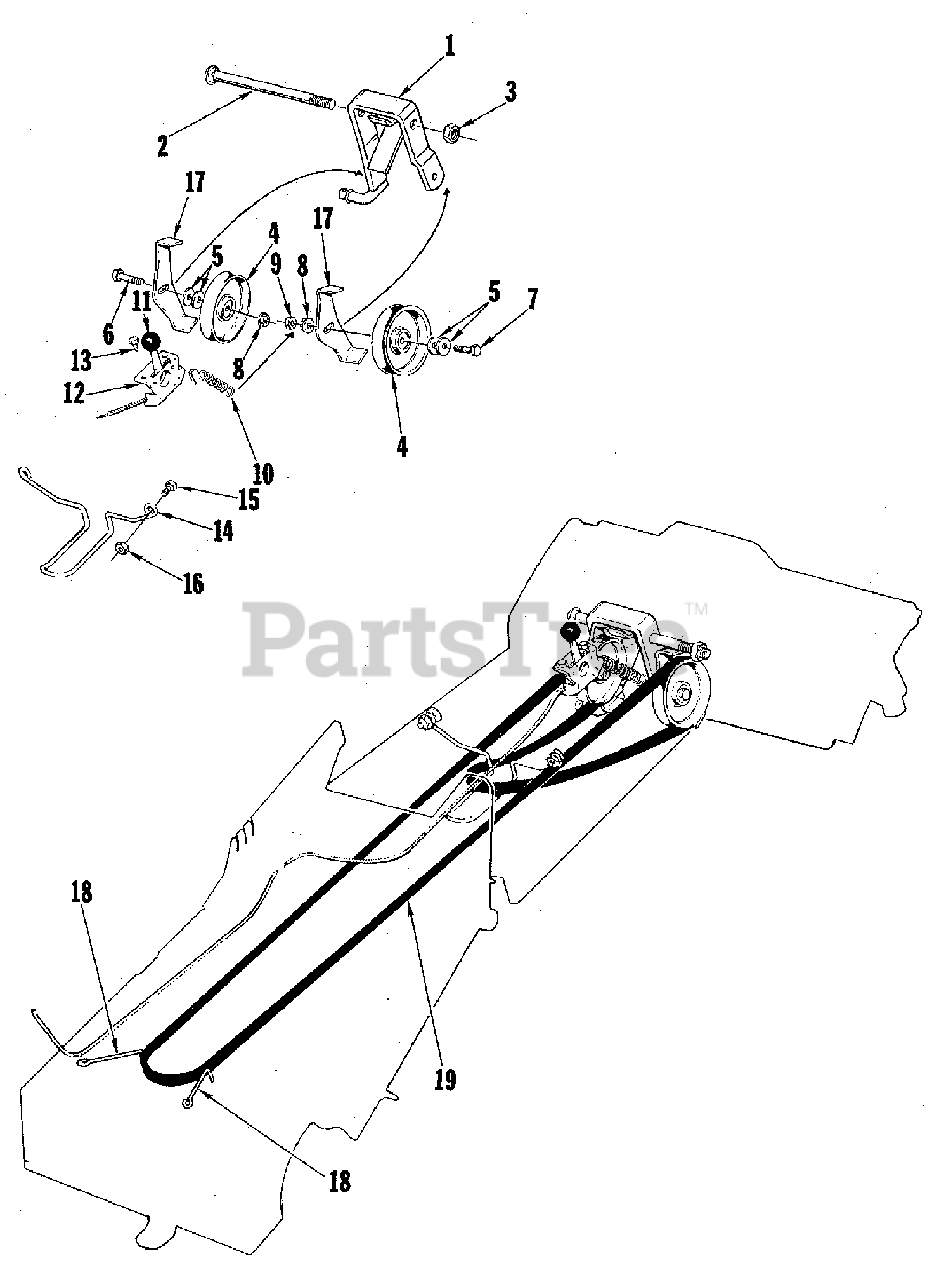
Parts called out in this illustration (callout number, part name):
1	BRACKET, Front, PTO
2	BOLT, Carriage, 1/2-13 x 8
3	NUT, Lock, 1/2-13
5	WASHER, Special
6	SCREW, Hex, 3/8-16 x 1-3/4
7	SCREW, Hex, 3/8-16 x 2
8	NUT, Flange, 3/8-26
9	NUT, Lock, 3/8-16
12	CONTROL, Throttle
13	SCREW, Taptite, 1/4-20 x 3/8
15	SCREW, Hex, 5/16-18 x 7/8
16	NUT, Hex Lock, 5/16-18
